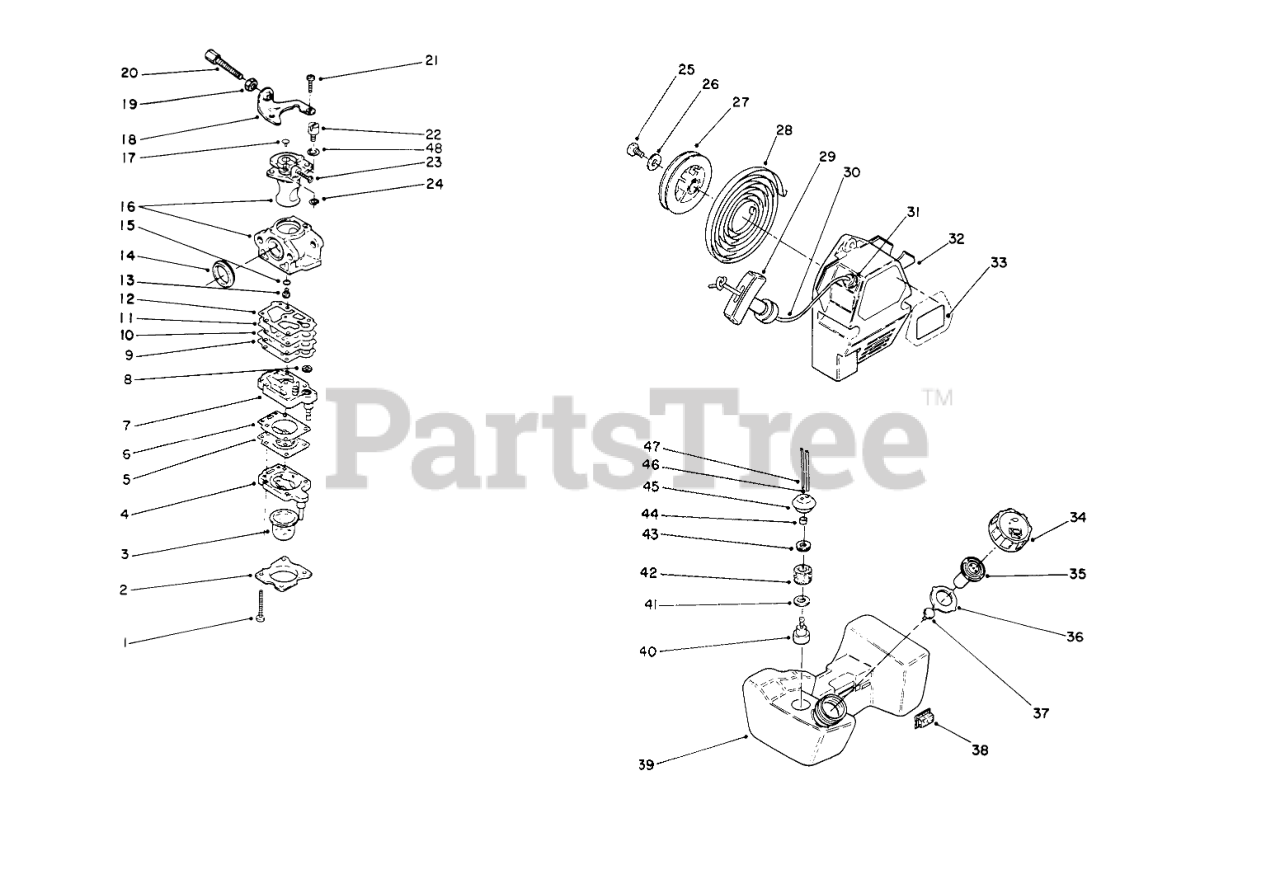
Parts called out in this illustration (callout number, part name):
1	SCREW
2	Cover-Primer
3	PRIMER PUMP
4	PRIMER BODY
5	DIAPHRAGM
6	DIAPHRAGM GASKET
7	Body-Pump (Incl. Ref. #8)
8	SCREEN
9	PUMP GASKET
10	Plate
11	DIAPHRAGM
12	DIAPHRAM GASKET
13	MAIN JET
14	RUBBER CARB GASKET
15	MAIN JET O-RING
16	Body-Carburetor (Ref.)
18	BRACKET
19	LOCKNUT
20	ADJUSTING SCREW
21	SCREW
22	Holder-Wire
23	THROTTLE VALVE
25	SCREW
26	WASHER
28	SPRING
29	Knob-Starter
30	Rope-Recoil
31	GUIDE
32	RECOIL CASE
33	Decal-Toro
34	FUEL TANK CAP
35	BREATHER VALVE
36	PACKING
39	Tank Assembly-Fuel (Incl. Ref. #34-37 & 40-47)
40	Weight-Filter
42	Filter-Fuel
43	Washer-Seal
44	COLLAR
45	FUEL TANK GROMMET
46	TUBE, FUEL
47	RETURN FUEL HOSE
48	WASHER
